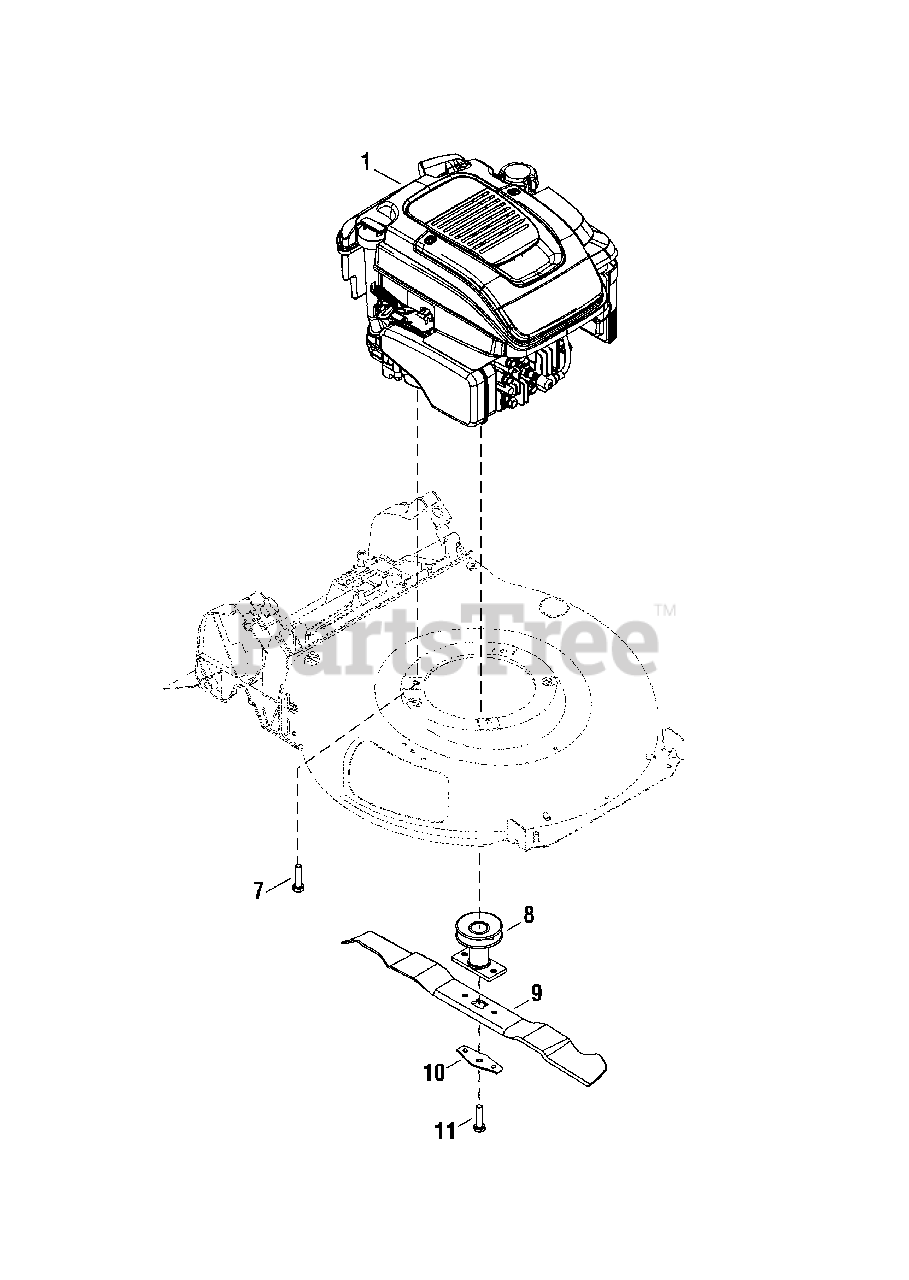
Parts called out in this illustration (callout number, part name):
1	* ENGINE, Briggs & Stratton, Mod. 111P05-0008-F1
7	SCREW, Engine Mounting, 3/8-16 x 1
8	ASSEMBLY, Blade Adapter
9	BLADE, Mulching
10	SUPPORT, Blade Bell
11	SCREW Hex, 3/8-24 x 1-1/2
